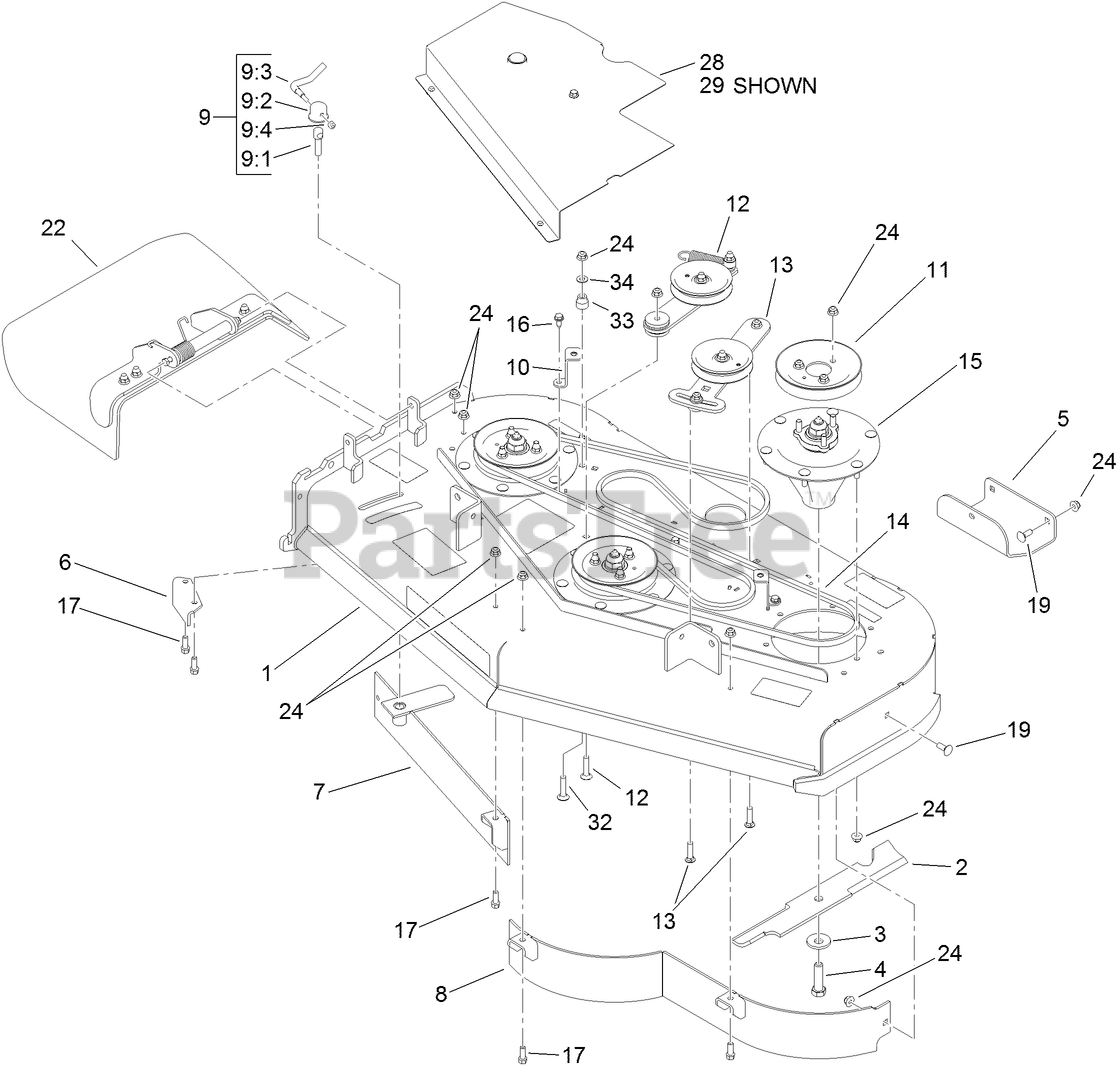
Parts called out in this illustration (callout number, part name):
1	DECK ASM
2	BLADE-16.5 INCH (HIGH FLOW)
3	Washer-Blade Bolt, Heavy
4	SCREW-BLADE
6	BAFFLE-DISCHARGE
7	BAFFLE ASM
8	48 INCH BAFFLE ASM
9	LEVER ASM
9:1	Screw-Lock
9:2	CAP-LOCK
9:3	Lever-Lock
9:4	NUT-LOCK, NI
10	BELT COVER BRACKET ASM
11	PULLEY
12	IDLER ARM ASM
13	IDLER ADJUST ASM
14	BELT-V
15	SPINDLE ASM
16	SCREW-HWHTF
17	SCREW-HWH
19	BOLT-CARR
22	DEFLECTOR ASM
24	NUT-HF, NI
28	LH BELT COVER ASM
29	RH BELT COVER ASM
32	SCREW-CARR
33	BUSHING-IDLER
34	WASHER-FLAT
